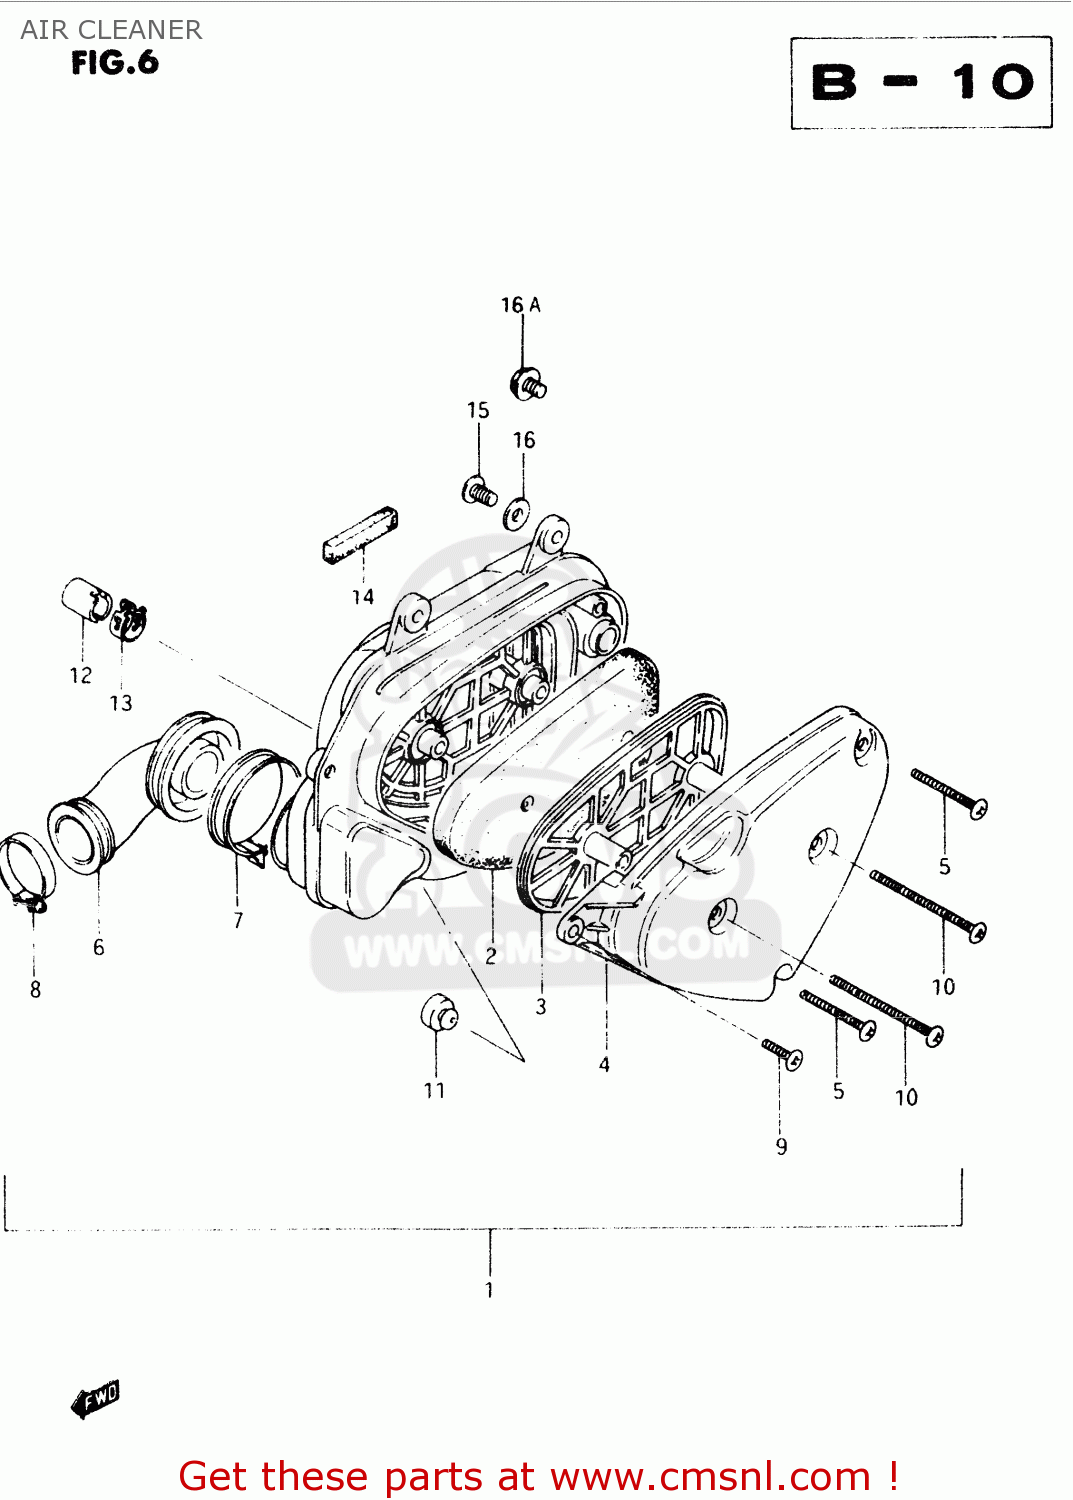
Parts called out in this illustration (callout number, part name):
1	CLEANER ASSY
2	FILTER
3	HOLDER,AIR FILTER
4	CAP,AIR CLEANE
5	SCREW
6	TUBE,AIR CLEANER OUTLET
7	CLAMP
8	CLAMP
9	SCREW
10	SCREW
11	STOPPER
12	TUBE,DRAIN
13	CLIP
14	CUSHION
15	SCREW
16	WASHER
16A	SCREW(6X16)
